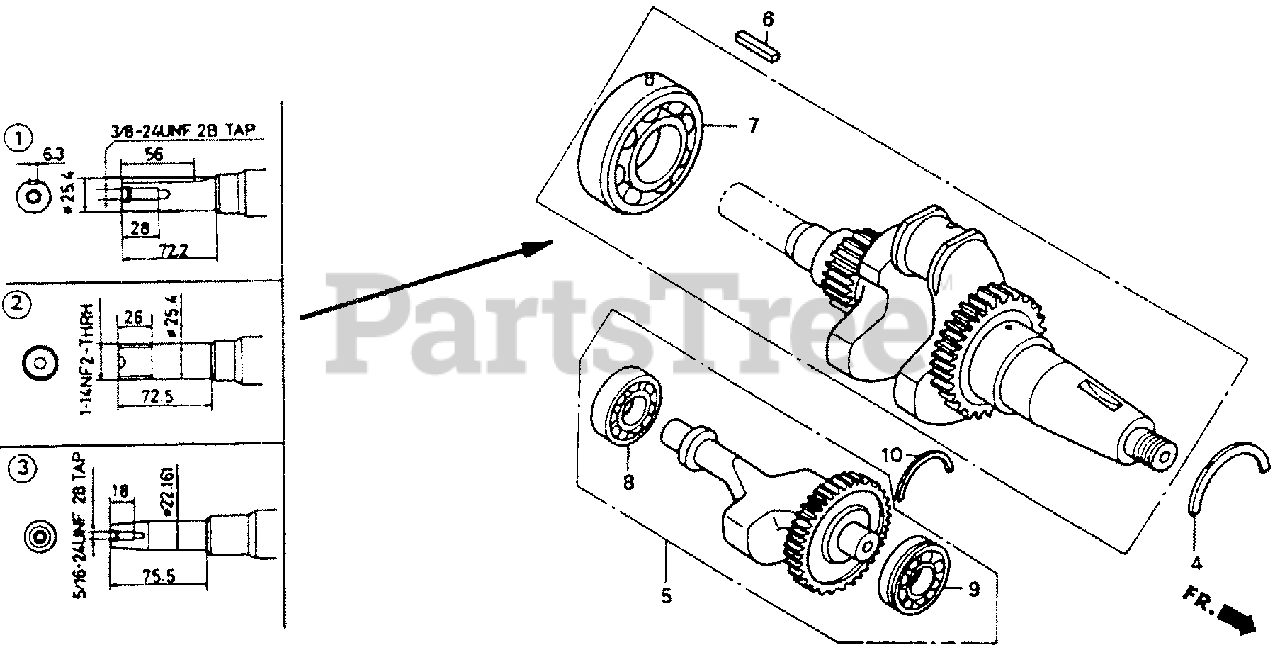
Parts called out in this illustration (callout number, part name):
2	CRANKSHAFT (P-TYPE)
4	BEARING A, CRANKSHAFT THRUST (BLUE)
4	BEARING B, CRANKSHAFT THRUST (BLACK)
4	BEARING C, CRANKSHAFT THRUST (BROWN)
4	BEARING D, CRANKSHAFT THRUST (GREEN)
4	BEARING E, CRANKSHAFT THRUST (YELLOW)
4	BEARING F, CRANKSHAFT THRUST (PINK)
5	WEIGHT, BALANCER
7	BEARING, SPECIAL (6308) (NTN CORP.)
8	BEARING B, SPECIAL BALL (6304)
9	BEARING C, SPECIAL BALL (6304)
10	SET-RING (520)
